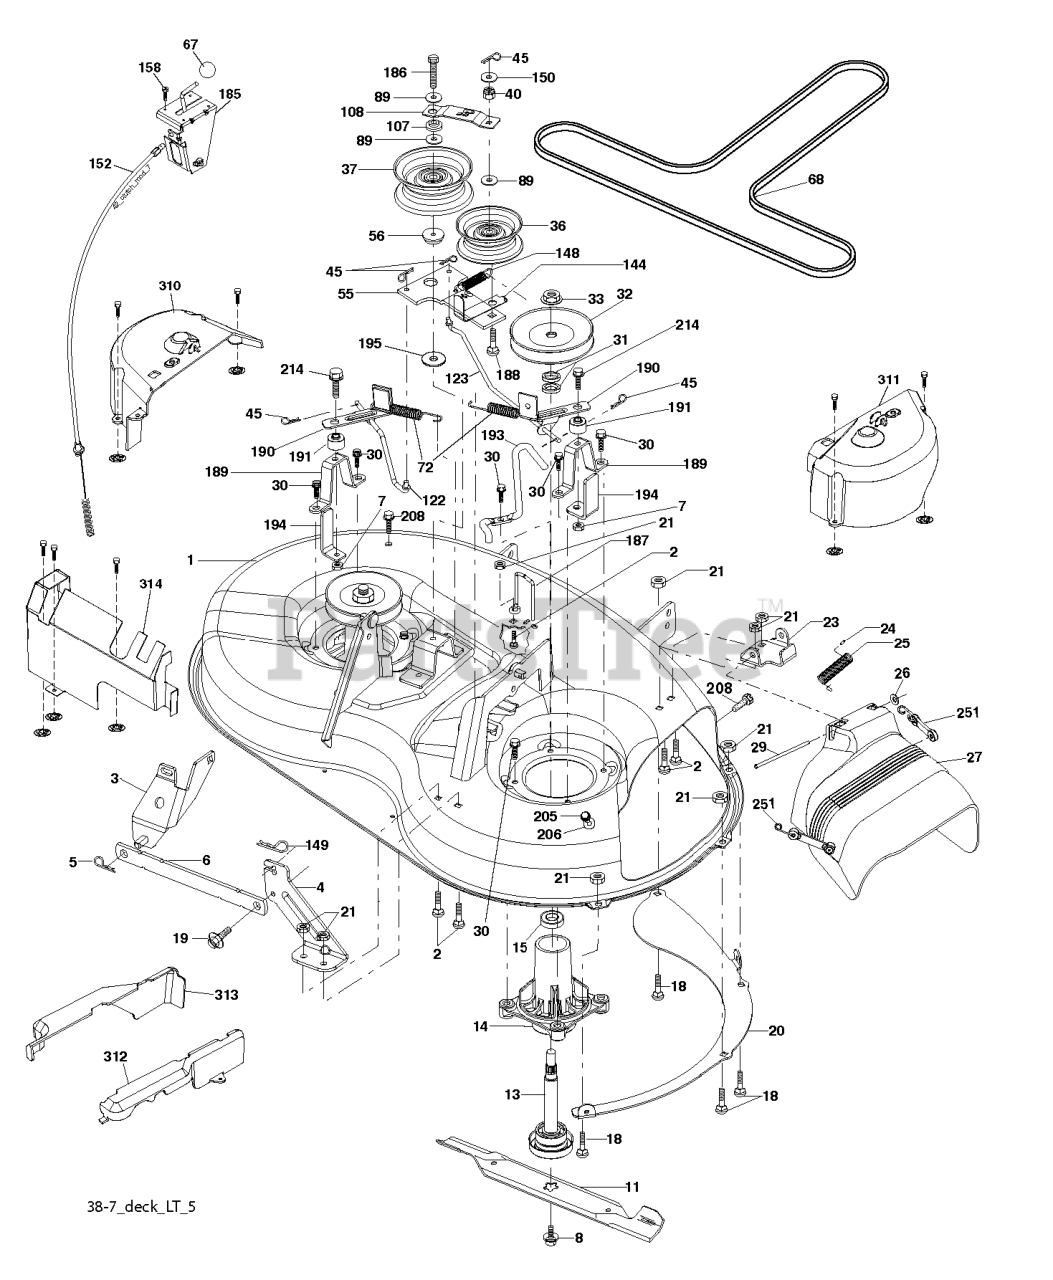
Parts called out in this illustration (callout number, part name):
1	DECK SVCX1 38/94 192556X431
2	RP BOLT 5/16-18 X3/4 ZN/YEL GR
3	BRKT ASM SWAY BAR
4	BRACKET DECK SWAY BAR 38"/42"
5	RETAINER-SPRNG RB
6	BAR SWAY DECK
7	NUT.71038.31-18.HEX.NYLOCK
8	BOLT.WASHER.ASM.7/16-2
11	BLADE 38" PREMIUM
13	SHAFT.ASM.MDRL.N/GREASE.38
14	RP.HOUSING.MANDREL.4PT.
18	BOLT
19	BOLT SHD 5/16-18
20	BAFFLE.VORTEX.FRONT.38"
21	LOCKNUT
23	BRKT.DEFLECTOR.38"2005+
24	CAP-SLEEVE LT
25	SPRING.TORSION.DEFLECT
26	NUT PUSH M
27	SHIELD ASM.DFLCTR MWR.38-7"BLK
29	ROD.HINGE
30	SCREW, WASHER HEAD
31	WASHER.SPACER.MANDREL
32	PULLEY MANDREL
33	NUT.FLANGE.LOCK.TOP
36	FLAT IDLER PULLEY
37	PULLEY.IDLER.FLAT.UNPLATED
45	RETAINER M
56	SPACER.RETAINER.MOWER
67	KNOB T (3/8 HOLE)
68	V-BELT.MOWER.38"2005+
72	SPRING.BRAKE.RETURN.38"
89	WASHER
107	SPACER.IDLER.ARM
108	STIFFENER.IDLER.ARM
122	LINK.BRAKE.38"LEFT.2007
123	LINK.BRAKE.38"RIGHT
144	KEEPER BELT
148	IDLER RETURN SPRING
149	SPRING.RETAINER.YELLOW.ZINC
152	CABLE.CLUTCH.38".SERVICE
158	SCREW
185	HEAD ASM. CABLE CLUTCH
186	SCREW.HXWSH.3/8
187	KEEPER BELT
188	BOLT, CARRIAGE IDLER
189	STAND, BRAKE
190	ARM, BRAKE
191	BRAKE.SPACER.38".DECK
193	KEEPER BELT RH MANDREL
194	GUARD BRAKE
195	WASHER 12/32X2X10GA
205	SCREW
208	SCREW 3/8-16X1/2
214	BOLT/WASHER ASM 5/16-18
251	ELASTIC STRAP KIT
